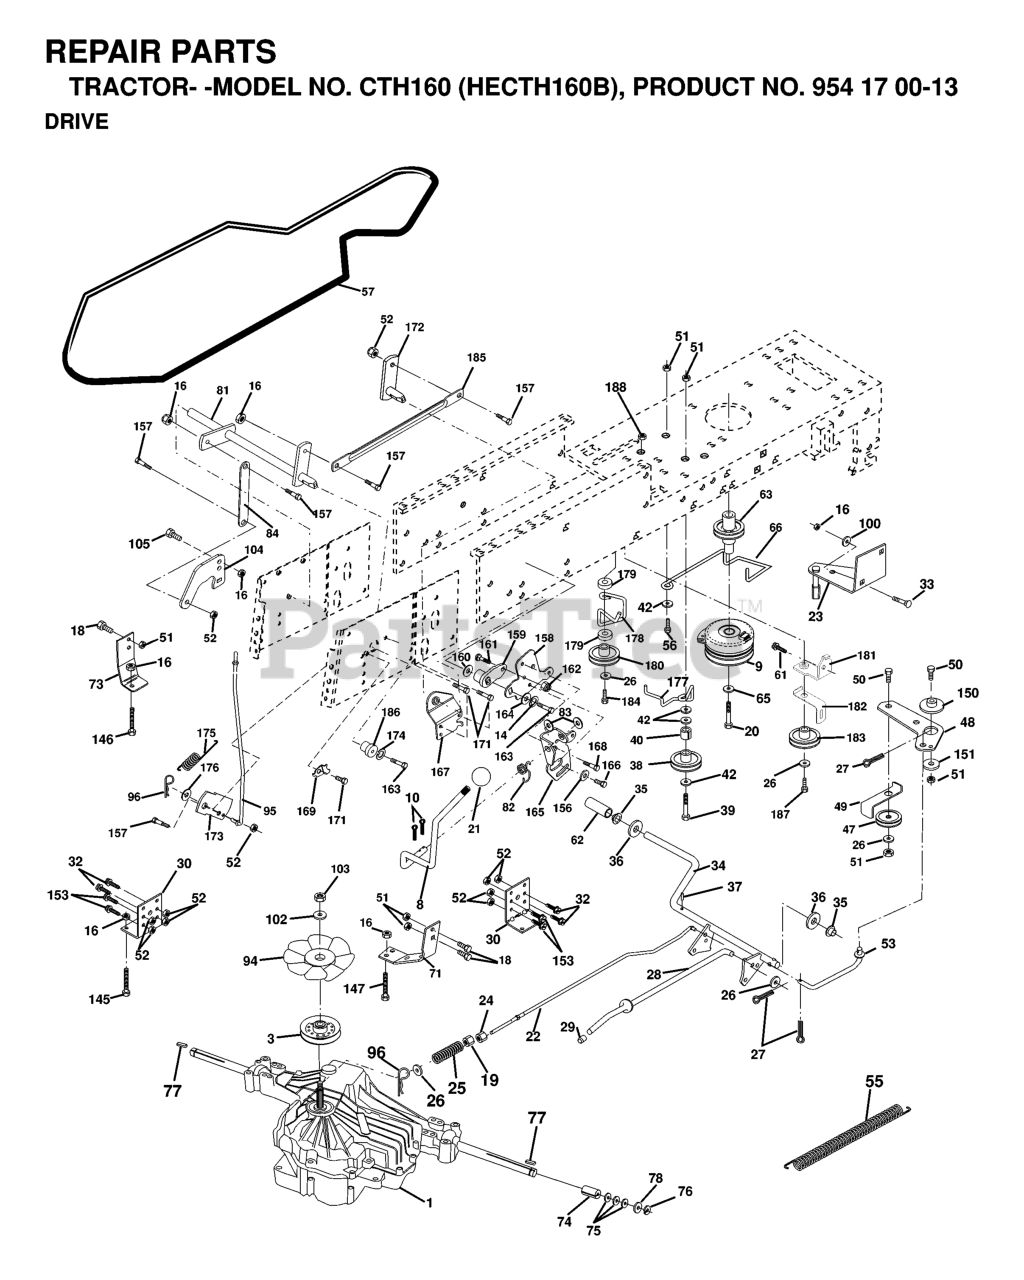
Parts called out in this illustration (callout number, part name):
3	PULLEY, TRANSAXLE
8	ROD.SHIFT.FENDER.ADJ.LT.CRD
9	CLUTCH
10	PIN COTTER
14	LOCKWASHER
16	NUT.71038.31-18.HEX.NYLOCK
19	NUT
20	BOLT HEX
21	KNOB.DUCKHEAD.1/2
23	BRACKET, ASM CLUTCH MTG
24	NUT
25	SPRING ROD LT
26	WASHER
27	COTTER PIN
28	ROD BRAKE PARK LT
29	PLUNGER CAP
30	BRACKET TRANSAXLE
32	BOLT
33	RP BOLT 5/16-18 X3/4 ZN/YEL GR
35	BEARING.NYLON
37	DRIVE PIN
38	PULLEY.FLAT
42	WASHER
47	IDLER PULLEY
48	BELLCRANK, CLUTCH
49	RETAIN BELT
50	BOLT
52	LOCKNUT
53	LINK, CLUTCH LT
55	SPRING, RETURN LT
57	V-BELT.0650.CRD.TRACTOR
61	SCREW
62	COVER, PEDAL (1 2)
63	PULLEY, CLUTCH ELECT EVX
65	LOCKWASHER
66	KEEPER BELT ENGINE
71	STRAP LH TORQUE
73	STRAP TORQUE RH HYDRO
74	SPACER SPLIT
77	SQUARE KEY
82	SPRING,TORSION
83	WASHER
84	LINK TRANSAXLE
94	FAN 7" HYDRO
95	BYPASS CONTROL ASM
96	RETAINER M
100	WASHER M
103	NUT.HEX.1/2-20
104	CONTROL ARM
146	Bolt Hex Flanged 5/16-18 Unc x 2
147	Bolt Hex Flanged 5/16-18 Unc x 2
150	BUSHING.BELLCRANK.GRD.DR
151	WASHER 12/32X2X10GA
153	BOLT RB
156	WASHER.SRRTD.5/16
157	BOLT SHOULDER 5/16-18
158	BRACKET
159	HUB
160	Washer 29/32 x 1 - 1/4 x 16 Ga.
161	BOLT
162	NUT.CROWNLOCK.1/4
164	Washer 5/8 x .281 x 10 Ga.
165	RP BRACKET
167	BRACKET.SUPT.SHIFT.CRD
168	BOLT.SHOULDER.5/16-18X
169	PLATE.FASTENING.CROSS.SHAFT
174	LOCKWASHER
175	SPRING.BYPASS.CRD
176	Washer 7/32 x 1/2 x 16 Gauge
180	PULLEY.FLAT.IDLER
181	BRKT.IDLER.GRD.DR.CRD
182	KEEPER BELT
183	PULLEY.V-IDLER
184	SCREW.HXWSH.3/8
186	HUB.TAPERED.ROUND.CRD
187	SCREW
188	SNAP BUSHING T
